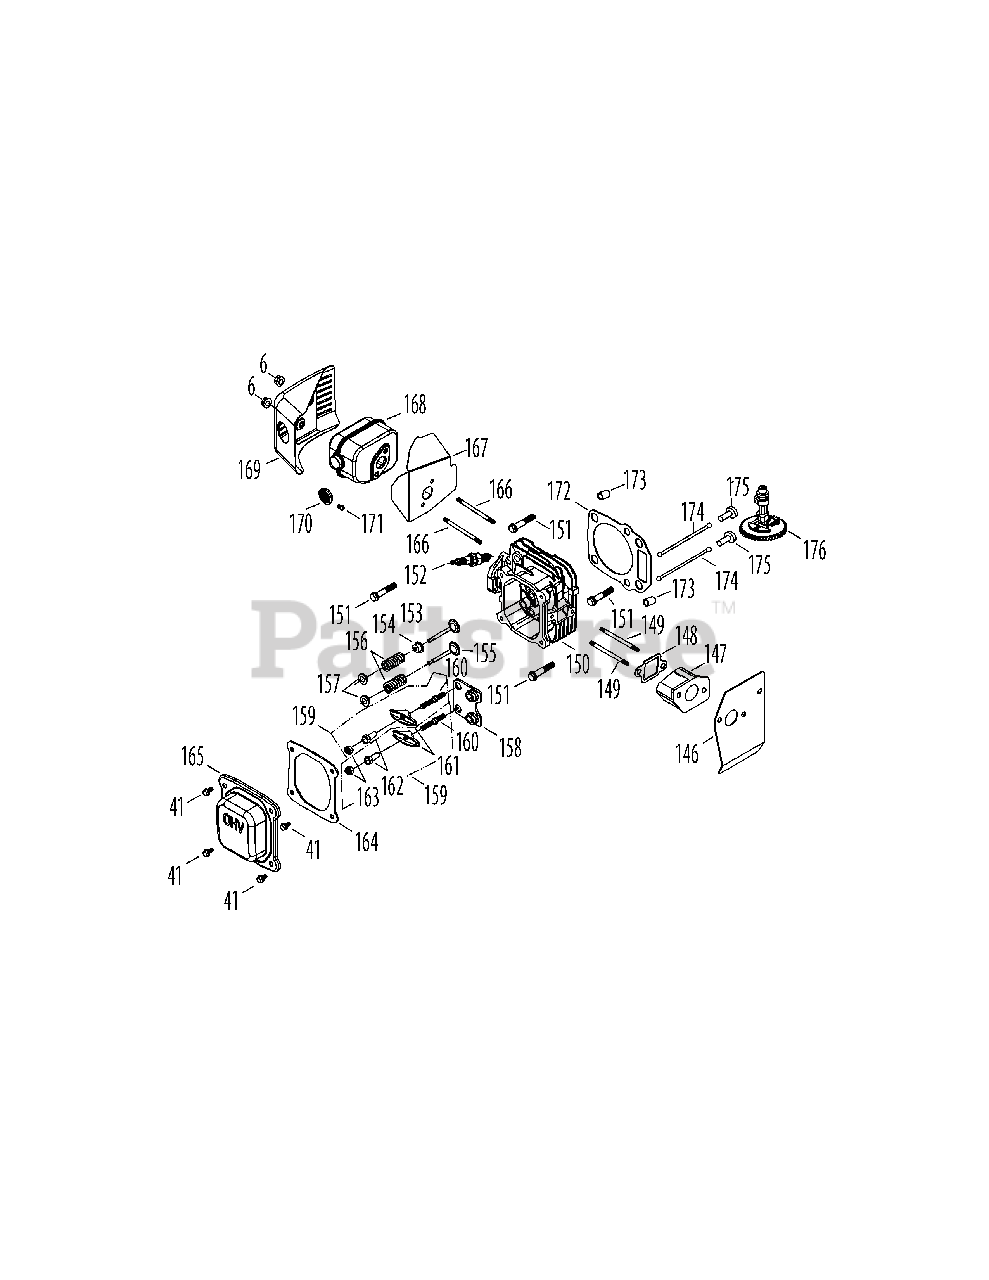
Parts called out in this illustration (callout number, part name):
6	Nut M6 X 10 Mm
41	Bolt M6×14
146	Carburetor Gasket
147	Carburetor Insulator
148	Carburetor Insulator Gasket
149	Carb Stud M6x113
150	Cylinder Head
151	Head Bolt M8×54
152	Spark Plug/F6rtc
154	Valve Seal
156	Valve Spring
157	Valve Spring Retainers
158	Push Rod Guide
159	Rocker Arm Assembly
160	Rocker Arm Stud
161	Rocker Arm
162	Fulcrum Nut
164	Valve Cover Gasket
165	Valve Cover
166	Muffler Stud M6x95
166	Muffler Stud Assemlby
167	Muffler Gasket
168	Muffler Assembly
169	Muffler Shield
170	Spark Arrestor
171	Spark Arrestor Screw
172	Cylinder Head Gasket
173	Cylinder Head Dowel 10×16
174	Push Rod Kit
176	Camshaft Assembly
